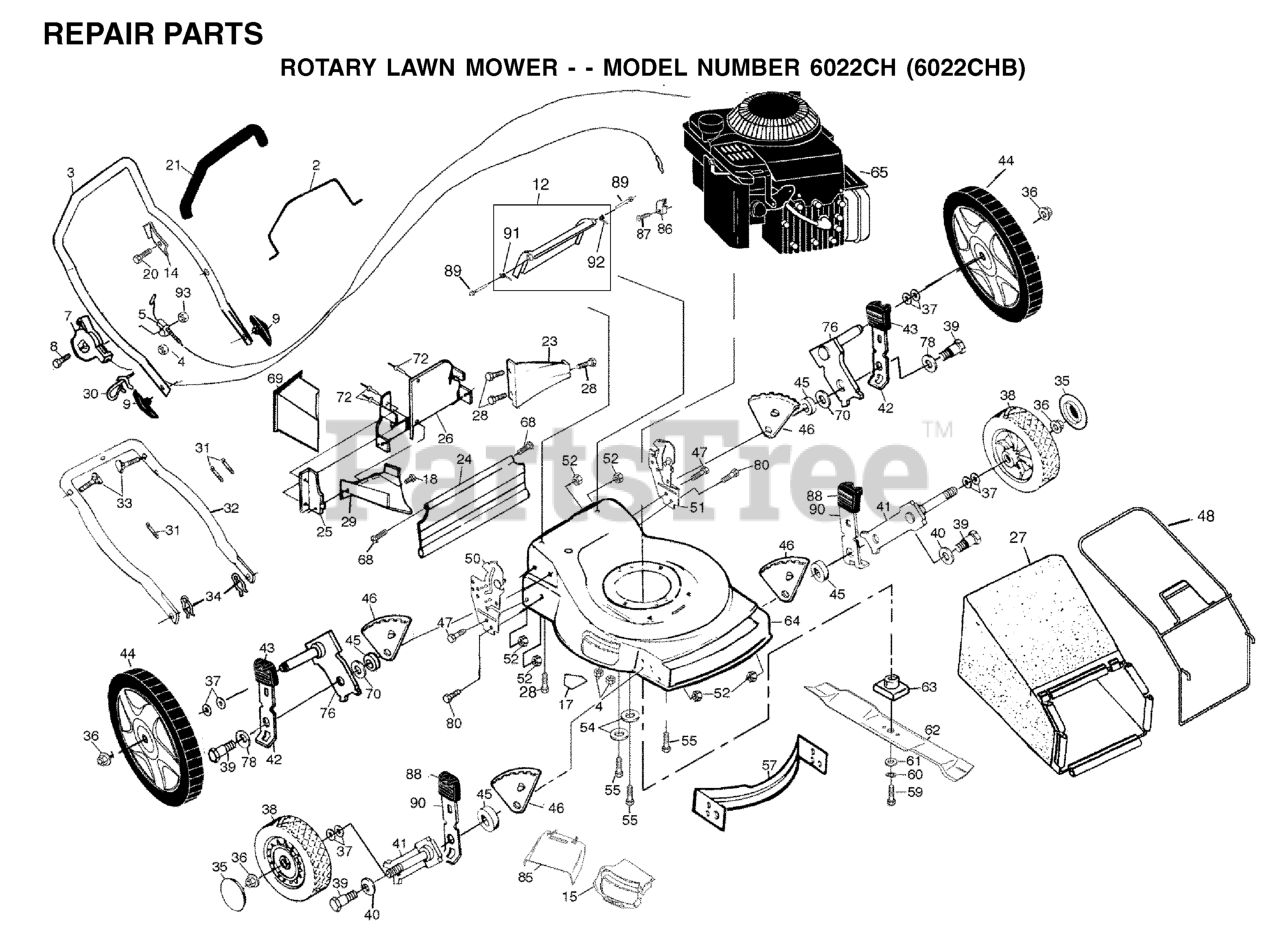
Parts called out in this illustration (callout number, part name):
2	CONTROL BAR
3	HANDLE, UPPER DLX COMF. (GRIP)
4	NUT
5	CABLE.MZR.51.RT.SP./PU.
7	THROTTLE CONTROL
8	SCREW 1/4-20 X 2.12
9	HANDLE KNOB
12	REAR DOOR KIT
14	BRACKET UPSTOP
17	DECAL HYT
18	SCREW.HXTAP.10-24
20	TAPPING SCREW
21	GRIP.HANDLE.FOAM
23	REAR BAFFLE
24	REAR SKIRT
25	SIDE BAFFLE
26	BACK PLATE
29	DISCHARGE BAFFLE
30	ROPE, GUIDE
31	TIE GUIDE
32	LOWER HANDLE
33	HANDLE BOLT
34	HAIRPIN COTTER
35	CAP.HUB.BLACK.WALK
36	HEX FLANGE LOCKNT
37	WAVE WASHER
38	WHEEL.8X2.PR.LP.RAD.GREY
39	BOLT
40	WASHER.BELLEVILLE (3 2 LB)
41	AXLE, REAR
44	WHEEL.14X2.PR.SP.RAD.GY
45	RP SPACER HT ADJ
46	WHEEL ADJ BRKT
47	SELF-TAPPING SCREW 5/16-18X3/4
48	CATCHER FRAME
52	LOCKNUT PM
54	WASHER.ENGINE.BZP
55	BOLT 3/8-16X1-1/8
59	SCREW, HEX HD 3/8-24 X 1-3/8
60	LOCKWASHER
61	WASHER,HARDEN
63	BLADE ADAPTOR
68	HINGE SCREW
69	PLUG.MULCH.22RD
70	WASHER.FLAT.1/2
72	RIVET BLIND
86	CABLE CLAMP(ENGINE)
87	SCREW.HEX.HEAD.WASHER.10-16
89	DOOR BOLT
90	SELECTOR SPRING
91	DOOR SPRING RH
92	DOOR SPRING LH
93	NUT
